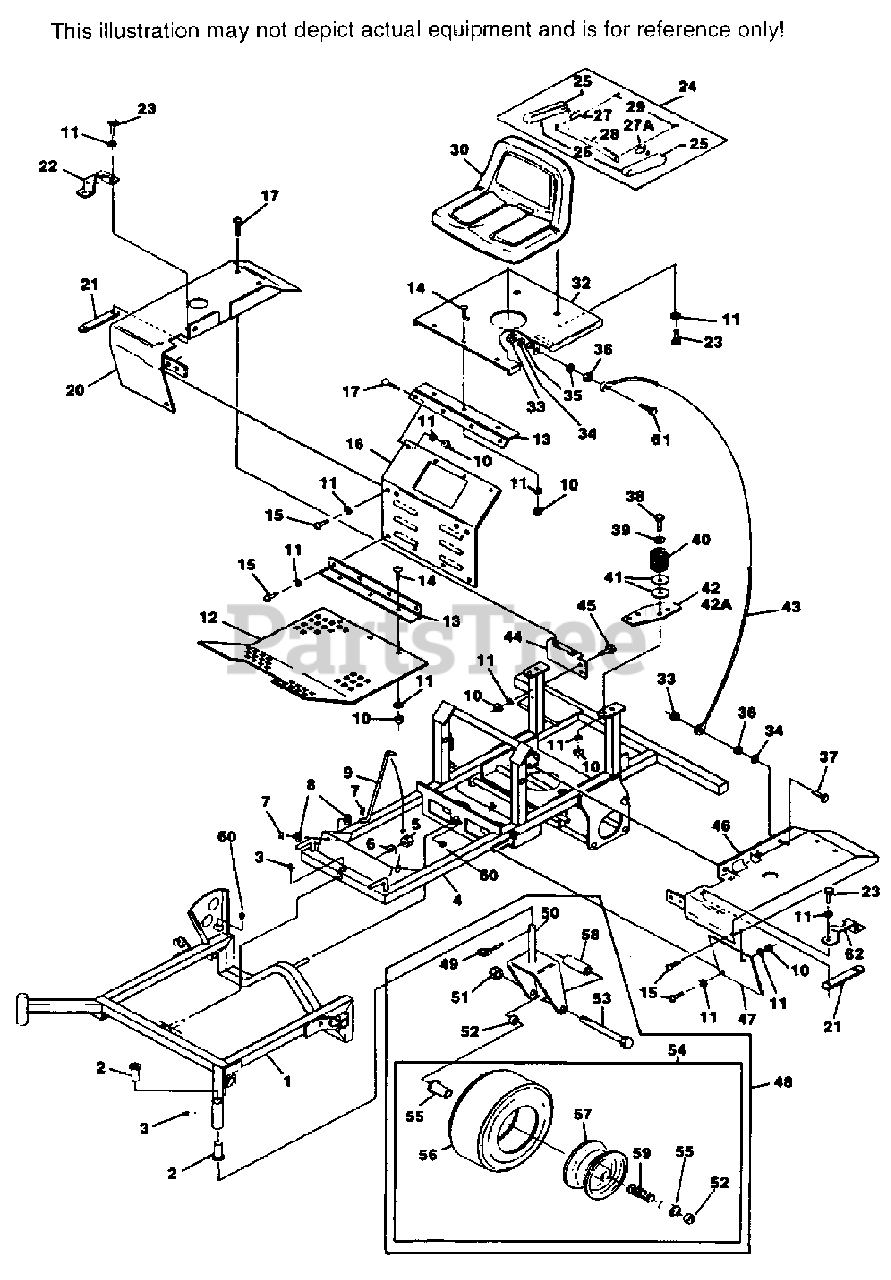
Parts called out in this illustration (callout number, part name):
1	CUTTER DECK SUPPORT FRAME ASSEMBLY
2	BUSHING
3	GREASE FITTING
4	MAIN FRAME(INCLUDES BUSHINGS & FITTINGS)
5	HEX NUT, 3/4-16 ELASTIC STOP
7	HAIR PIN, 1/16" DIA
9	ROD, FOOT PLATE LATCH
12	FOOT PLATE
13	HINGE
15	SCREW, 5/16-18 X 3/4 SOCKET BUTTONHEAD
16	KICK PLATE
20	FENDER - RH(METAL FUEL TANK)
20	FENDER - RH(PLASTIC FUEL TANK)
21	NEUTRAL LOCK BAR
22	NEUTRAL LOCK BRACKET, RH
24	ARM REST KIT(INC. 25,26,27,28,29)
25	SETSCREW, 3/8-16 X 3/4 FLAT POINT
26	ARM REST
27	MOUNTING BRACKET - RH
27A	MOUNTING BRACKET - LH
28	BACK STRAP
30	SEAT(INCLUDES 24 & 30A)
32	SEAT BASE
33	HEX NUT, 1/4-20 ELASTIC STOP
40	SEAT SPRING
41	FLAT WASHER, 13/32 X 1-1/2 X 7 GA.
42	OIL COOLER MOUNTING BRACKET - LH
42A	OIL COOLER MOUNTING BRACKET - RH
43	CABLE, SEAT STOP
44	FENDER BRACKET - RH & LH
46	FENDER - LEFT
47	LH FENDER EXTENSION
48	CASTER WHEEL ASSEMBLY, COMPLETE
49	QUICK PIN
50	CASTER WHEEL YOKE
51	HEX NUT, 1/2-13 ELASTIC STOP
52	SPACER
54	WHEEL ASSEMBLY, COMPLETE
55	BUSHING
56	TIRE ONLY
57	RIM ONLY
58	SLEEVE
59	ROLLER BEARING
60	GREASE FITTING
62	NEUTRAL LOCK BRACKET, LH
